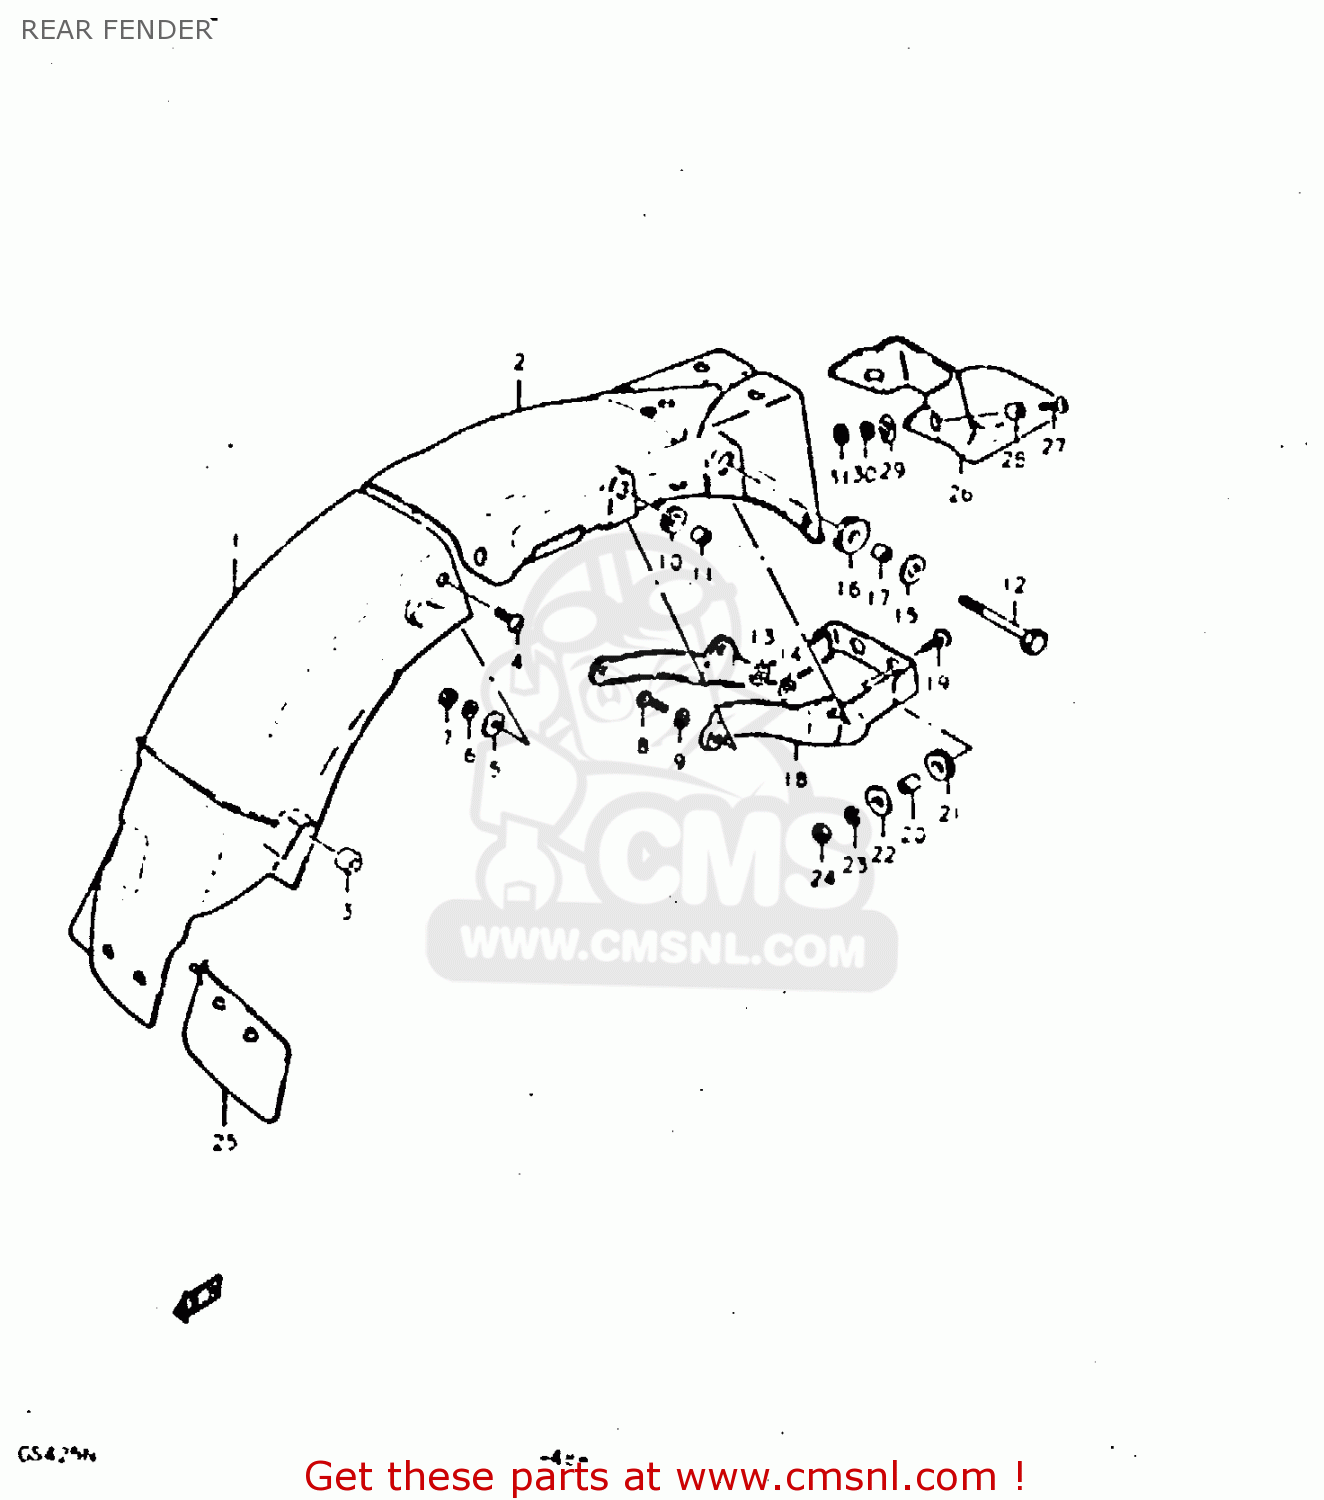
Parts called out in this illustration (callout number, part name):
1	FENDER,REAR
2	BODY,RR FENDER RR
3	CUSHION
4	SCREW
5	WASHER (5.5X16X1.2)
6	LOCK WASHER
7	NUT
8	BOLT
9	LOCK WASHER
10	CUSHION
11	SPACER(6.1X9X7.5)
12	BOLT
13	NUT
14	LOCK WASHER
15	WASHER(8.5X26X1.2)
16	CUSHION
17	SPACER (8.2X12X7.5)
18	REINFORCEMENT,REAR FENDER
19	SCREW
20	SPACER (6.1X9X9)
21	CUSHION
22	WASHER(6,5X22X1.6)
23	LOCK WASHER
24	NUT
25	MUD GUARD,REAR FENDER
26	EXTENSION,REAR FENDER
27	SCREW (6X15)
28	SPACER(6.2X8.3X5.7)
29	WASHER(6.5X18X1)
30	LOCK WASHER
31	NUT
